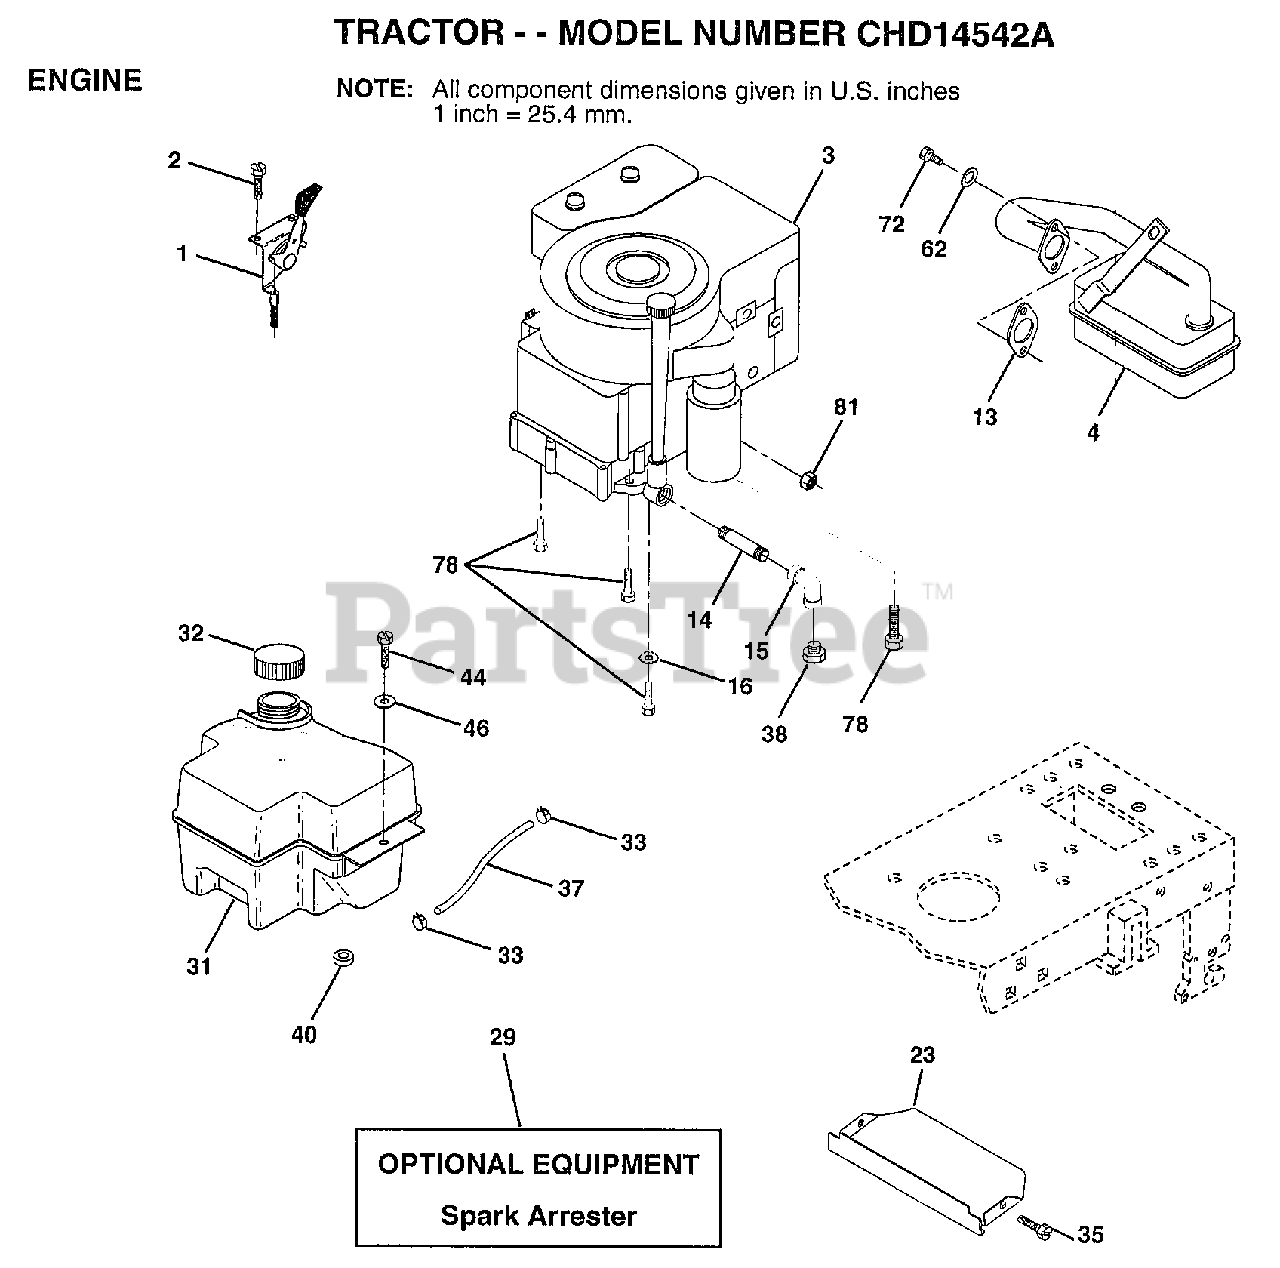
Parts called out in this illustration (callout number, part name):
1	CONTROL THROTTLE
2	SCREW LT
4	MUFFLER
14	PIPE NIPPLE
15	ELBOW
16	LOCKWASHER
23	SHIELD.BRN/DBR.GD
31	TANK.FUEL.FRONT.
32	CAP ASM FUEL
33	HOSE CLAMP
35	SCREW
37	LINE FUEL
44	SCREW HEX CRT
46	WASHER
62	LOCKWASHER
72	SCREW
78	SCREW
81	NUT
